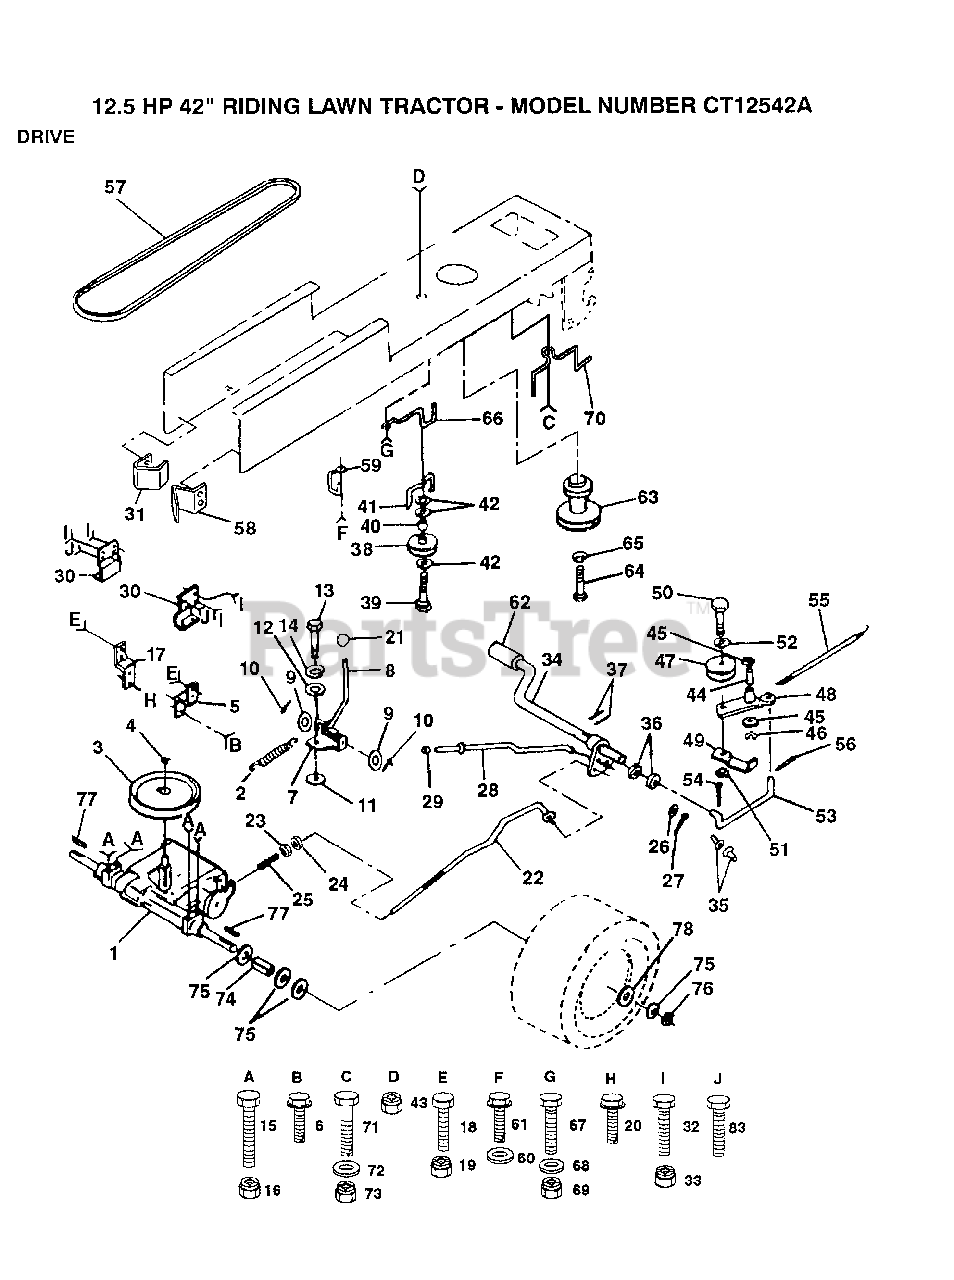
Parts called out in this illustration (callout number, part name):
3	PULLEY TRANS
5	STRAP TORQUE
6	SCREW
8	SHIFT ROD
9	WASHER
10	PIN COTTER 1/8
11	WASH-SHFT PLT LT
12	WASHER LT
14	LOCKWASHER
15	BOLT
17	STRAP TORQUE
20	SCREW
21	CONTROL KNOB LT
22	BRAKE ROD
23	NUT
24	NUT
25	SPRING ROD LT
26	WASHER
27	COTTER PIN
28	PARKING BRAKE ROD
30	TRANSAXLE MTG BKT
31	"KEEPER,BELT LH T"
32	BOLT
35	NYLON BEARING
36	WASHER LT
38	PULLEY.IDLER.FLAT
39	BOLT
40	SPACER T
41	BELT KEEPER LT
42	WASHER
44	"LY, BEARING"
45	WASHER LT
46	KLIP RING
48	ARM IDLER
49	RETAIN BELT
52	WASHER
53	"LINK, CLUTCH T"
54	COTTER PIN
55	"SPRING, RETURN LT"
56	COTTER PIN
58	"KEEPER,BELT RH T"
60	WASHER
61	SCREW
62	PEDAL COVER T
64	BOLT
65	LOCKWASHER
66	KEEPER.BELT.ENG.L
67	BOLT
68	WASHER
70	GUIDE BLT DR MWR
71	BOLT
72	WASHER
74	SPACER LT
75	WASHER
76	E-RING LT
77	SQUARE KEY
78	WASHER
83	SCREW
